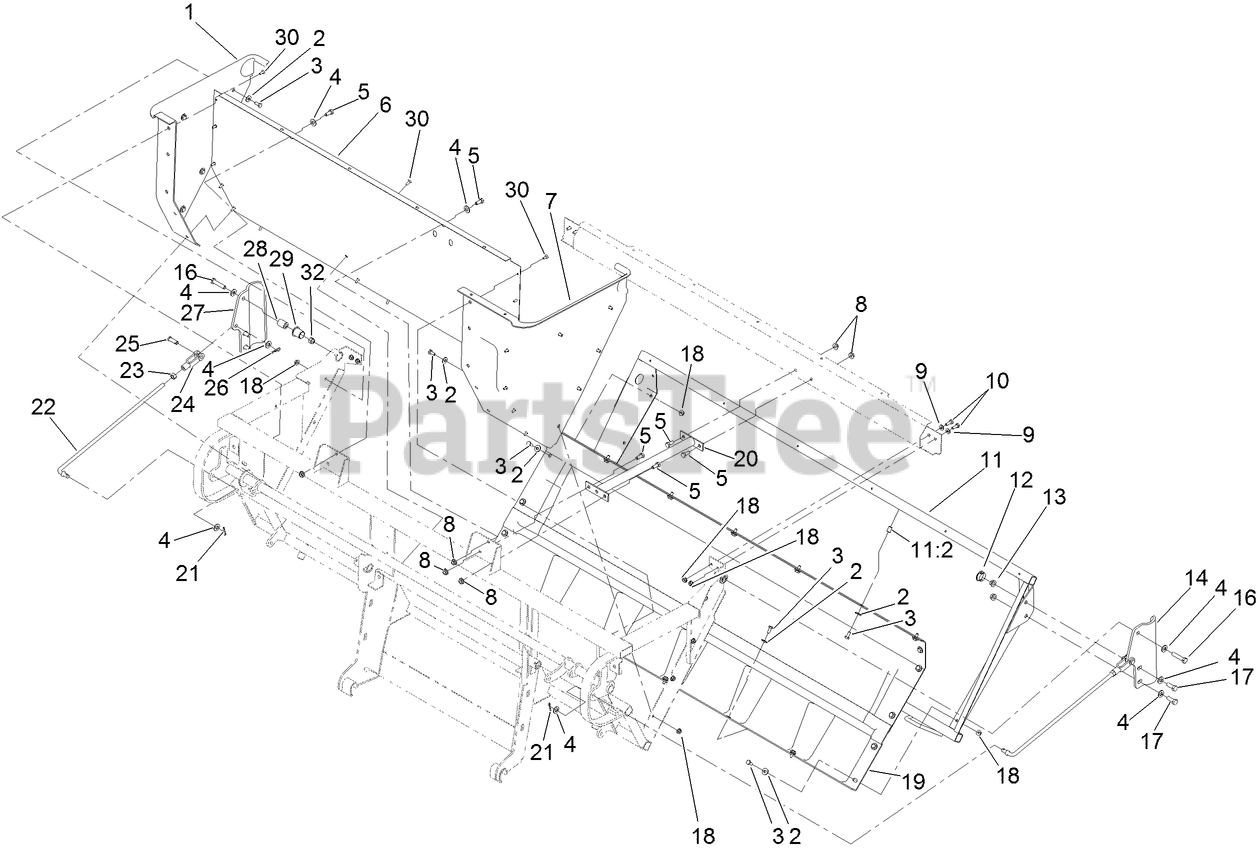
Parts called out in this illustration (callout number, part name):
1	PANEL-BAGGER, RH
2	WASHER-FLAT
3	SCREW-HH
4	WASHER-FLAT
5	SCREW-HH
6	SHEET-WALL
7	PANEL-BAGGER, LH
8	NUT-HF
9	WASHER-FLAT
10	SCREW-HH
11	DOOR ASM
11:2	NUT-CLINCH
12	PLUG-DOME
13	NUT-HHF, WHIZ
14	ARM-HINGE, LH
16	SCREW-HH
17	SCREW-HH
18	NUT-HF
19	BAG AND BOTTOM PANEL ASM
21	PIN-COTTER
22	LINK-HINGE
23	NUT-HEX
24	YOKE-LINKAGE, BRAKE
25	PIN-CLEVIS
26	PIN-COTTER
27	ARM-HINGE, RH
28	PIN-PIVOT, HINGE
29	BUSHING
30	RIVET-BLIND
32	NUT-LOCK, NI
